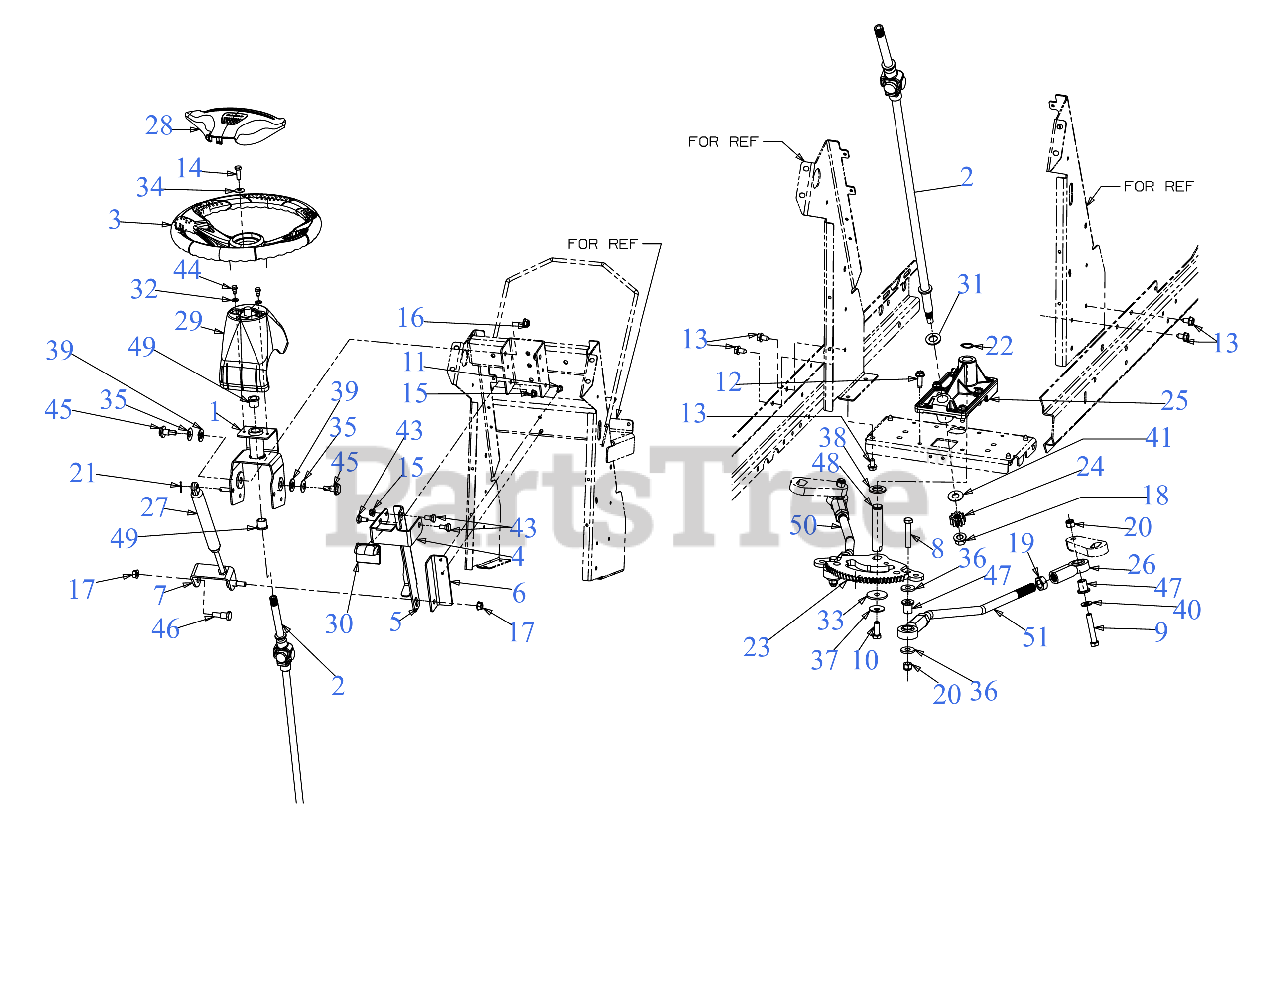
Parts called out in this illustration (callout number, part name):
2	STEERING SHAFT ASSEMBLY
3	STEERING WHEEL
7	DAMPER CYLINDER PIVOT BRACKET
8	HEX SCREW 3/8-24 X2.00
9	HEX SCREW 3/8-24 x 2.25 GR5
10	SCREW 3/8-24 x 1.00 GR5
11	SCREW 1/4-20 X.500
12	SCREW 5/16-18 x 1.00
13	SCREW 5/16-18 x .625
14	SCREW 5/16-18 x 1.00 GR5
15	FLANGE LOCK NUT 5/16-18
17	HEX LOCK NUT
18	FLANGE LOCK NUT
19	HEX JAM NUT 5/8-18
20	INSERT NUT 3/-24
21	COTTER PIN-3/32 DIA x .75
22	SNAP RING FOR .750 DIA SHAFT
23	STEERING GEAR SEGMENT
24	STEERING PINION GEAR
25	STEERING HOUSING ASSEMBLY
26	BALL JOINT ROD END
27	DAMPER CYLINDER
28	STEERING WHEEL COVER
29	STEERING COLUMN
30	TILT WHEEL LEVER
31	FLAT WASHER .635 ID x 1.12 OD x .090
32	FLAT WASHER .344 ID x .62 OD x .033
33	FLAT WASHER
34	BELL WASHER .337 X.867 x .057
35	BELL WASHER
36	FLAT WASHER .385 x 1.00 x .135
37	BELL WASHER .390x1.130x.062
38	SHIM WASHER .76X1.25X.10
39	FLAT WASHER
40	FLAT WASHER
41	FLAT WASHER
43	SHOULDER SCREW .437 DIA x .180
44	SHOULDER SCREW 1/4-20X.50 19"PSH
45	BOLT-SHLDR .49 DIA x .50
46	SHOULDER BOLT .50 DIA x .66
47	SHOULDER SPACER
48	STEERING SHAFT SEGMENT
49	FLANGE BEARING
50	STEERING DRAG LINK (LH)
51	STEERING DRAG LINK (RH)
